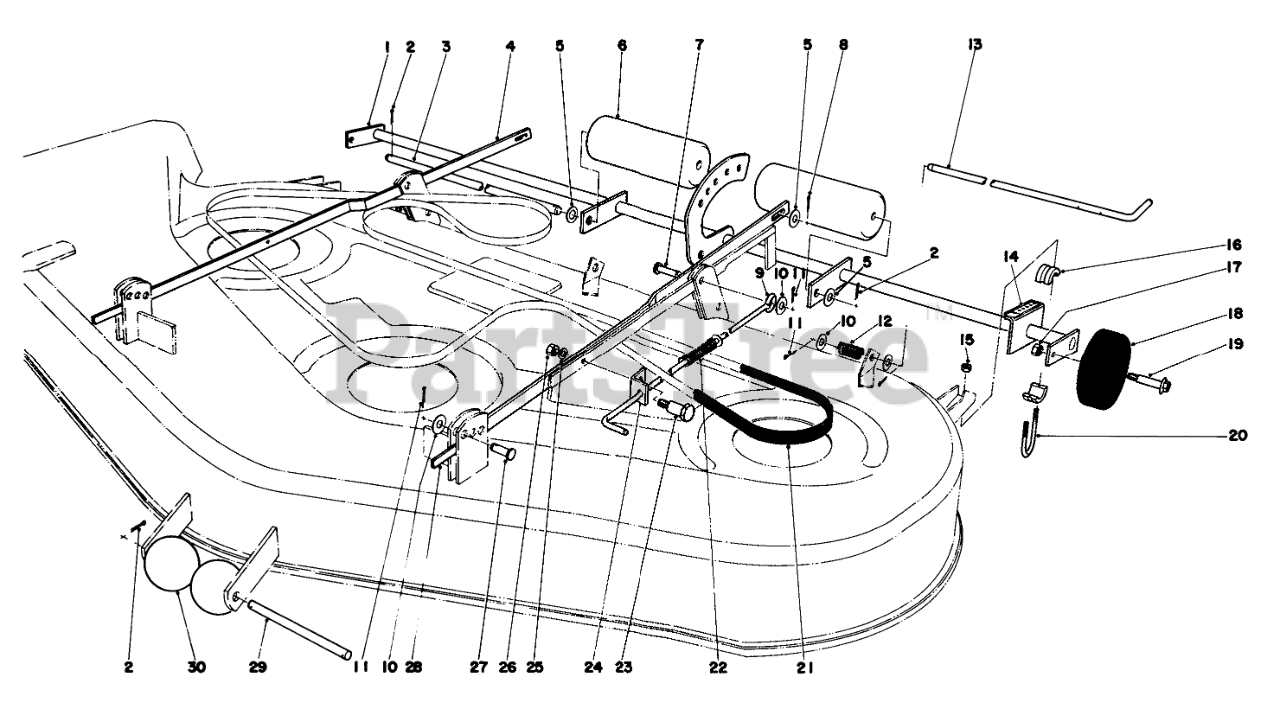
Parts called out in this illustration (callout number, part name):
1	DECK WHL SHAFT WA B
2	PIN-COTTER
3	ROLLER SHAFT B
4	RR SCISSORS LNK B
5	WASHER-FLAT
6	ROLLER-DECK
7	PIN-CLEVIS
8	PIN-COTTER
9	Pin Tension
10	WASHER-FLAT
11	PIN-COTTER
12	Spring
13	WHEEL LATCH ROD B
14	Decal-Height of Cut
16	BEARING DECK SH WHEEL
17	Nut
18	DECK WHEEL
20	U-BOLT
21	V-BELT, DECK
22	COMP SPRING
23	Bolt-Shoulder
24	TENSION BELT BRKT B
25	WASHER-PLAIN
26	NUT-LOCK, CONE
27	PIN-CLEVIS
28	Scissors Link Rear L.H.
29	ROLLER SHAFT
30	Roller
